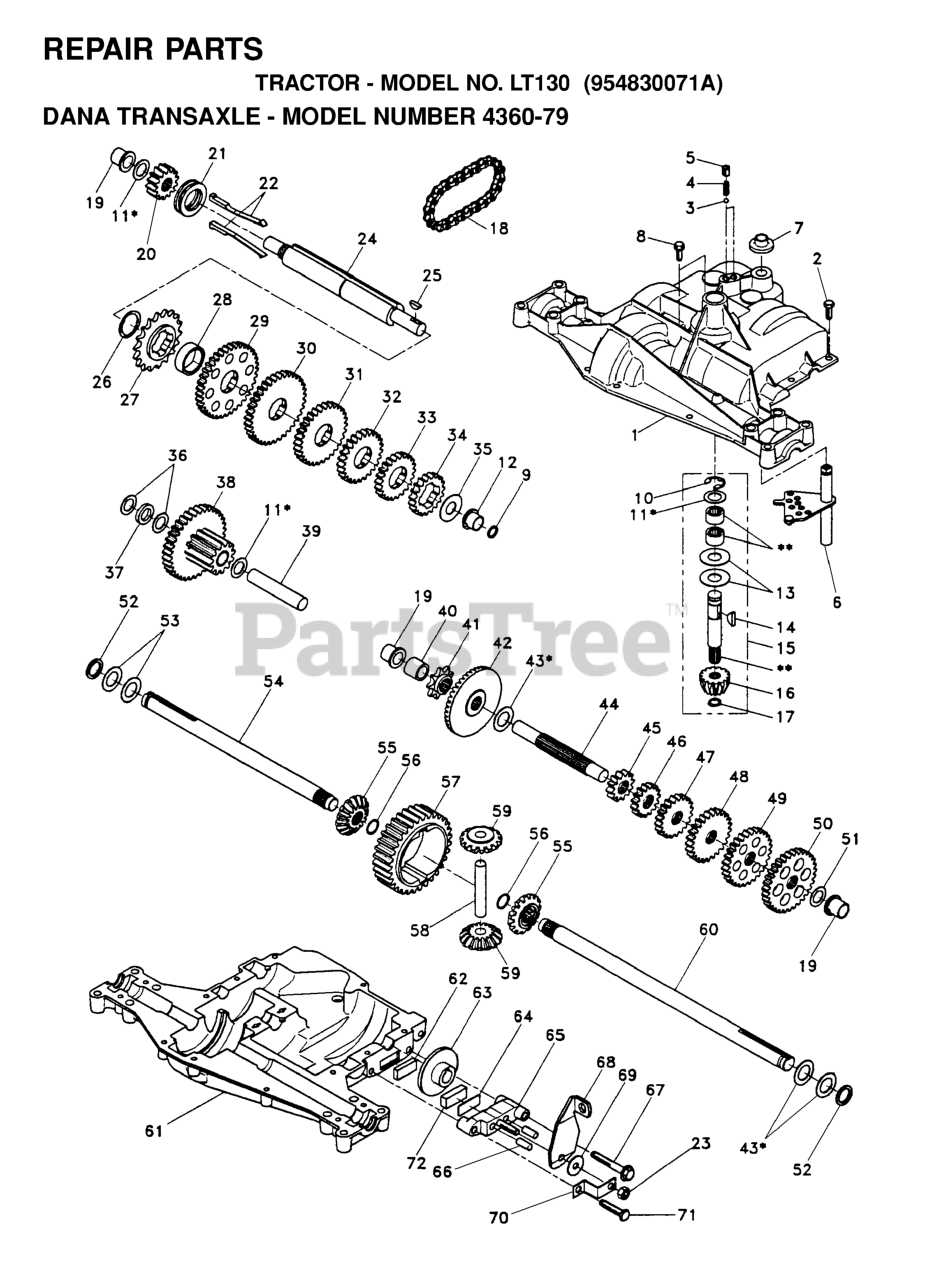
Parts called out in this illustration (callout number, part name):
1	HOUSING, UPPER
3	DETENT, BALL
4	SPRING, DETENT
6	SHIFTER KIT
7	BOOT, SHIFTER
8	SCREW, SELF TAPPING W/SEALER
9	SQUARE RING
10	RING, RETAINING
11	SHIM.KIT.DANA.4689
12	Bearing, Flange
13	WASHER.PLAIN..632X1.38X.046
14	KEY.WOODRUFF.DANA
15	AS KIT INPUT SHFT
16	PINION 14T
17	RING RETAINING
18	CHAIN 24 PITCH LT
19	BEARING, FLANGE LT
20	GEAR SPUR 14 TTH
22	ASSEMBLY KIT, CLUTCH KEYS
23	LOCKNUT
24	SHAFT INTERM DANA
25	KEY, WOODRUFF, #61
26	RING, RETAINING LT
27	SPROCKET 18T
29	GEAR, SPUR 37 TEETH
30	GEAR, SPUR 35 TEETH
32	GEAR, SPUR 25 TEETH
33	GEAR, SPUR 22 TEETH
36	WASHER 025
38	ASSM GEAR COMB T NLA
39	SHAFT IDLER
41	SPROCKET 9T LT
42	GEAR 42T
44	SHAFT, DRIVE
46	GEAR SPUR 15T DANA
49	GEAR, SPUR 28 TEETH
50	GEAR, SPUR 31 TEETH
52	NEOPRENE.WASHER.DANA
53	WASHER, PLAIN .758 X 1.25X.031
54	AXLE T, LH
55	GEAR 15T T
56	RING, RETAINING
59	GEAR 1ST T
61	LOWER HOUSING
62	PUCK, FRICTION
63	BRAKE DISC T
65	JAW T
67	SCREW, SELF TAPPING, LARGE
68	LEVER ACTUATOR
69	WASHER, PLAIN .321 X 1.00X.055
70	BRACKET, ANTI ROTATION
72	PUCK, FRICTION
73	SHELL, GREASE
